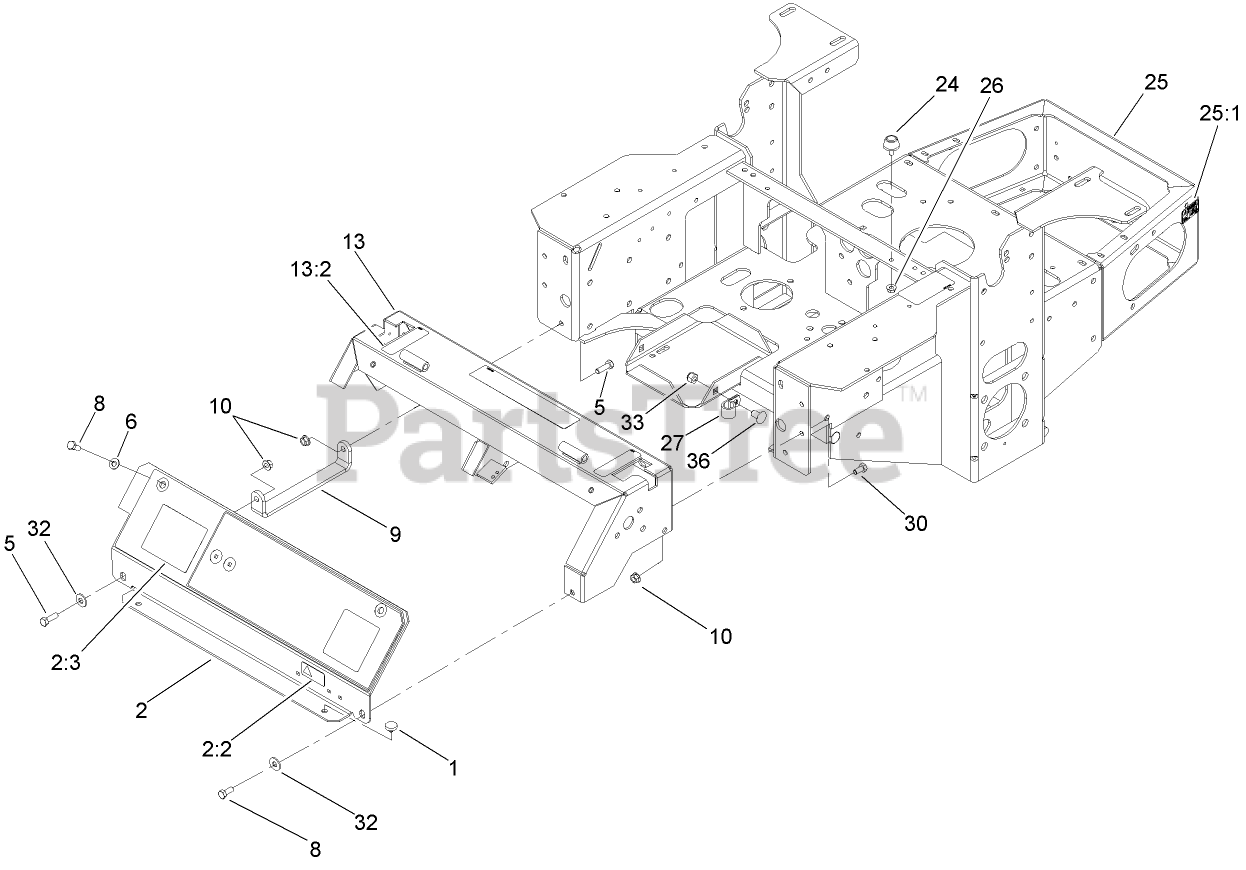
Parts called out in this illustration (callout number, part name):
1	BUMPER
2	PANEL ASM
2:2	DECAL-PROTECTION, EAR
2:3	DECAL-COVER, PANEL
5	SCREW-HH
6	WASHER-PLAIN
8	SCREW-HH
9	BRACKET-PANEL, INSTRUMENT
10	NUT-HF
13	CONSOLE ASM
13:2	DECAL-WARNING
24	BUMPER-RUBBER
25	MAIN FRAME ASM
25:1	DECAL-SURFACE, HOT
26	NUT-HF
27	CLIP-LOOM
30	SCREW-HH
32	WASHER-FLAT
33	NUT-LOCK, NI
36	SCREW-CARR
